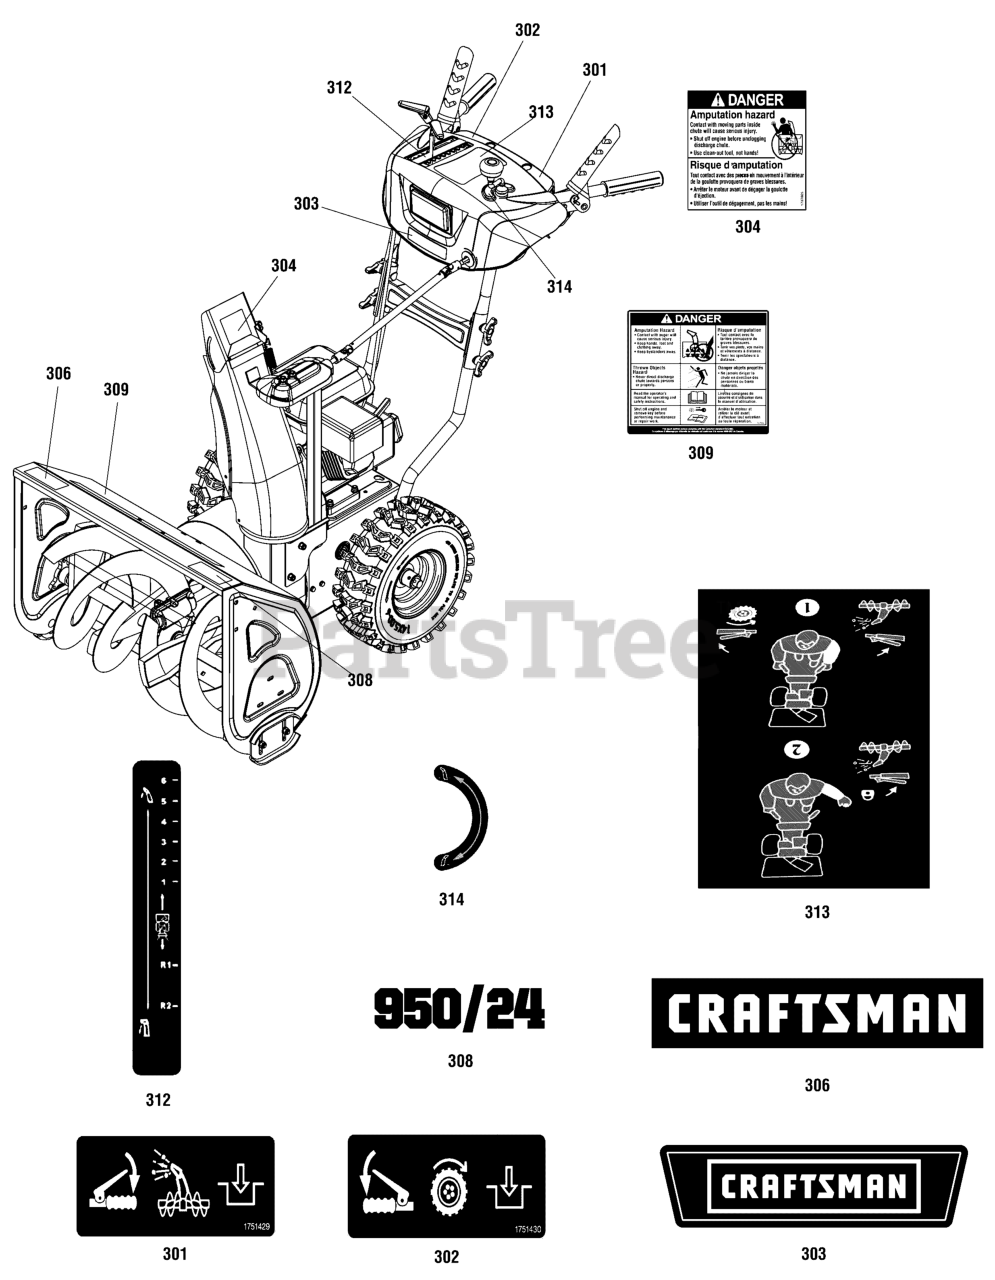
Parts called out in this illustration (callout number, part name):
1	KIT-DECAL, Craftsman 950/24
301	*DECAL, Auger Control
302	*DECAL, Traction Control
303	*DECAL, Control Panel, Craftsman
304	DECAL, Danger Chute
306	*DECAL, Craftsman Logo
309	DECAL, Danger Foot
312	*DECAL, 1-6 Transmission Speed Control
313	*DECAL, Free Hand Operation
314	*DECAL, Chute Rotation
